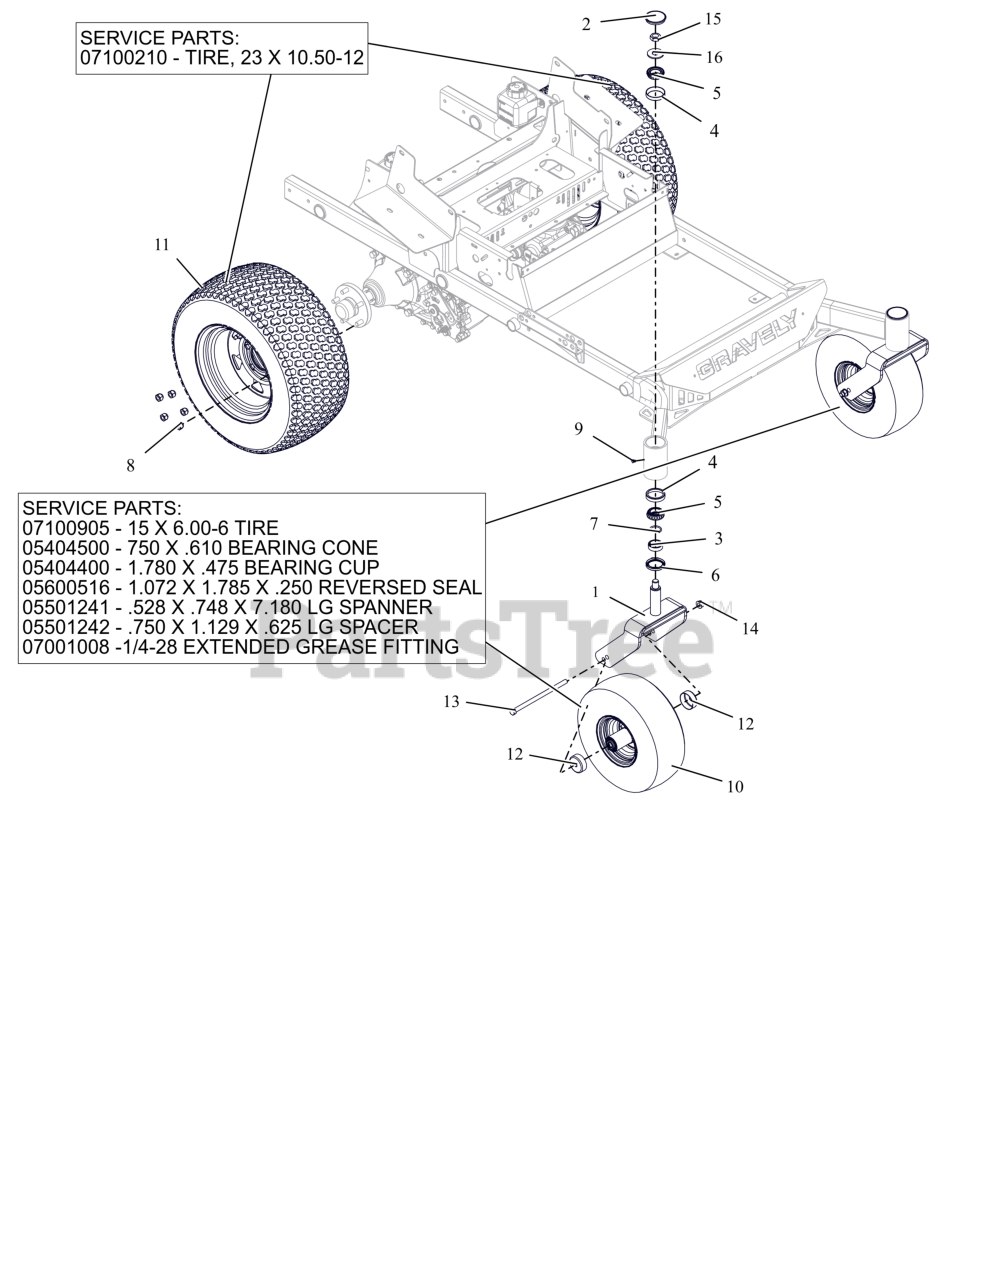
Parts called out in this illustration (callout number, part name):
1	CASTER FORK WMT - RED
2	CAP, DUST
3	SPCR, FRONT CASTER FORK
4	BRG-CUP 2.328X.465
5	BRG-CONE 1.25X.66
6	SEAL, OIL 1.75 X 2.332 X .312
8	NUT, WHEEL .50-20 ZCC
9	FTG, .25-28 FLUSH MNT GREASE
10	ASM, WHL/TIRE 15X6.00-6 SMOOTH
10	TIRE, 15X6-6 SMOOTH
10	BRG-CONE .750X.61
10	BRG-CUP 1.781X.475
10	SEAL,1.072X1.785X.250 REVERSED
10	SPANNER, .528X.748X7.18 LG
10	SPACER, .750X1.129X.625 LG
10	GREASE FITTING 1/4-28 EXTENDED
11	ASM, WHL/TIRE 23X10.50-12 K500
11	TIRE, 23X10.00-12
12	SHIELD, WHEEL BEARING
13	BLT, HEX .50-13X9.00 G5 ZCC
14	NUT-LK-TOP-FLG .500-13 GF ZCC
15	NUT, JAM-TOPLOCK .750-16 ZCC
16	WSHR-FL-STL 0.812X2X0.148 ZCC
